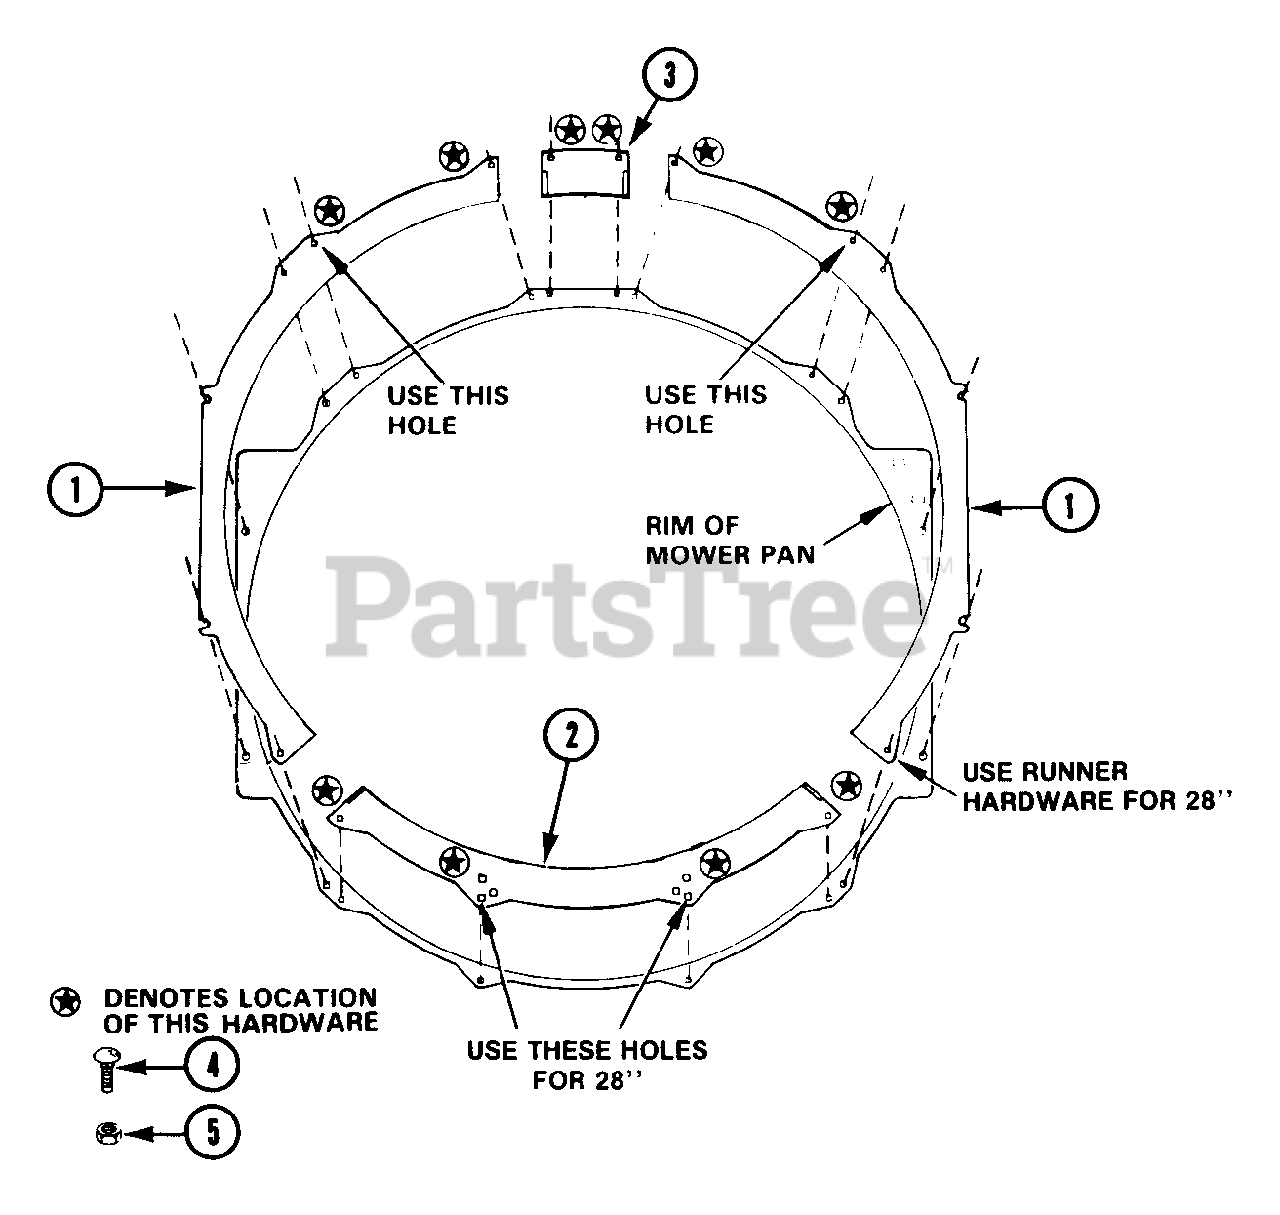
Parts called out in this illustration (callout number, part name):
1	SIDE FLANGE
2	BACK FLANGE
3	BRACE
4	BLT-RDHDSQNK .25-20X.62 PL
5	NUT-LK-CTR .250-20 PL
